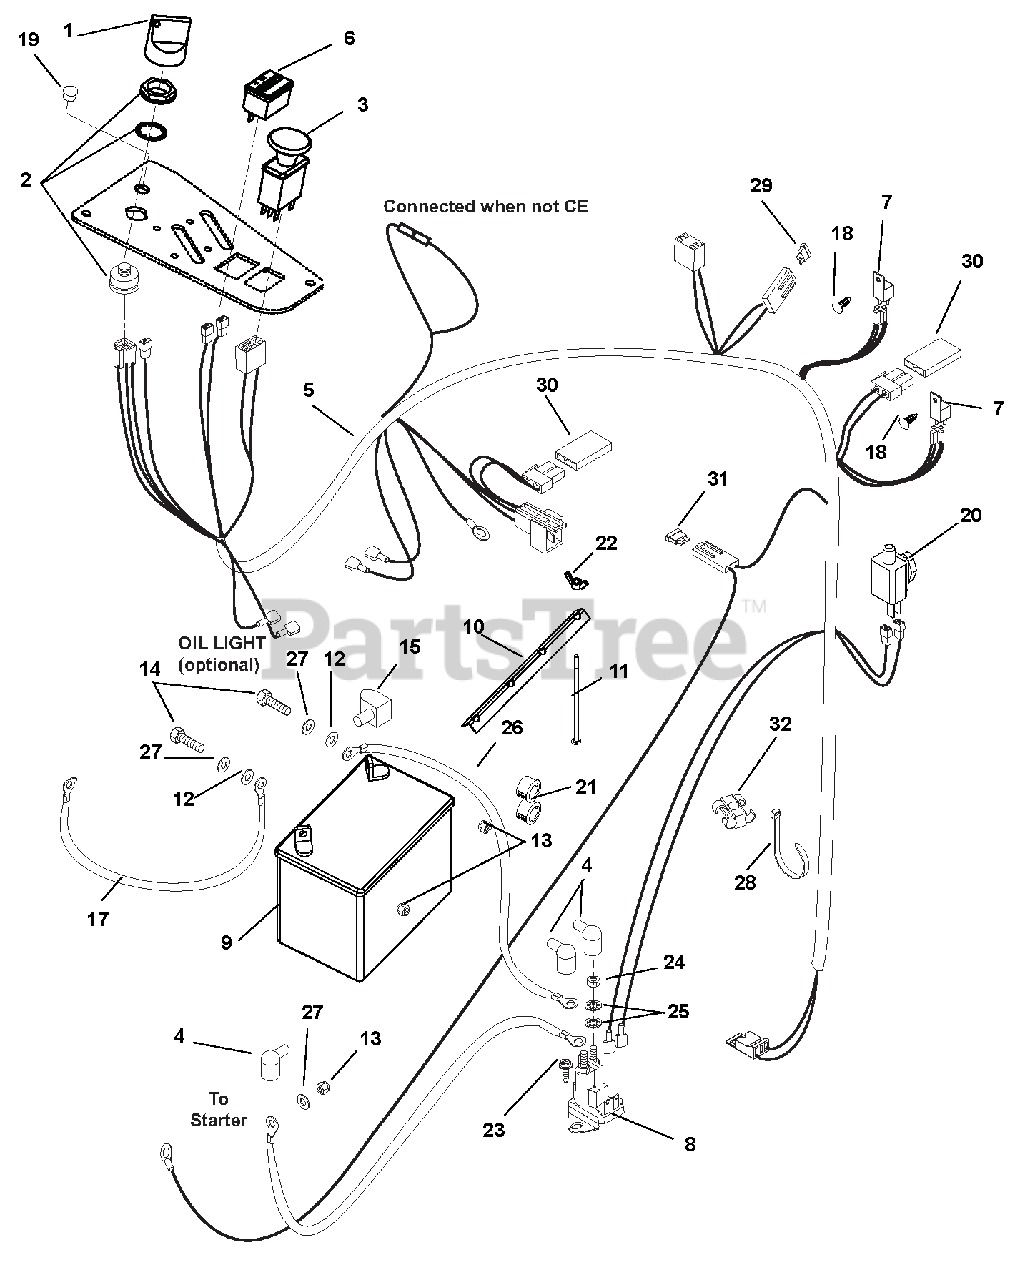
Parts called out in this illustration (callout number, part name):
1	KEY, W/ SHIELD
2	SWITCH, IGNITION
3	SWITCH, CLUTCH
4	BOOT, BATTERY TERMINAL-RED
5	HARNESS - CZ REMOTE SOL.
6	METER, HOUR W/MAINTENANCE
7	RELAY,SEALED W/DIODE
8	SOLENOID, HP RTV
9	BATTERY, 300 CCA 10U1L
10	HOLD DOWN
11	BLT-RDHDSQNK .25-20X7.50 GR2YZ
12	@WSHR-FL-STL.281X.62X.065 YWZC
13	@NUT-HEX .25-20 YWZC
14	@BLT-HEX .25-20X.75 GR5 YWZC
15	INSULATOR
16	CABLE-POSITIVE BATTERY 9.00"
17	CABLE-NEGATIVE BATTERY 24.00"
18	RIVET, .25 NYLON PANEL
19	PLUG-HOLE .50 DIA
20	SWITCH, SINGLE POLE N.O.
21	BUSH, PANEL SNAP .687X.875X.56
22	NUT-LK WING .250-20 YWZC
23	@SCR-TAP .25-20X.50 HWH TR YWZ
24	NUT-JAM .31-24 YWZC
25	@WSHR-LK-EXT.326X.599X.031YWZC
26	CABLE, STARTER .31X23.00X.31
27	@WSHR-LK .25X.062 REG YWZC
28	CABLE TIE LG 5-1/2
29	FUSE 20AMP
30	DIODE, CONNECTOR SHELL
31	FUSE-25 AMP ATC TYPE
32	CLIP,T,.31-.38,
